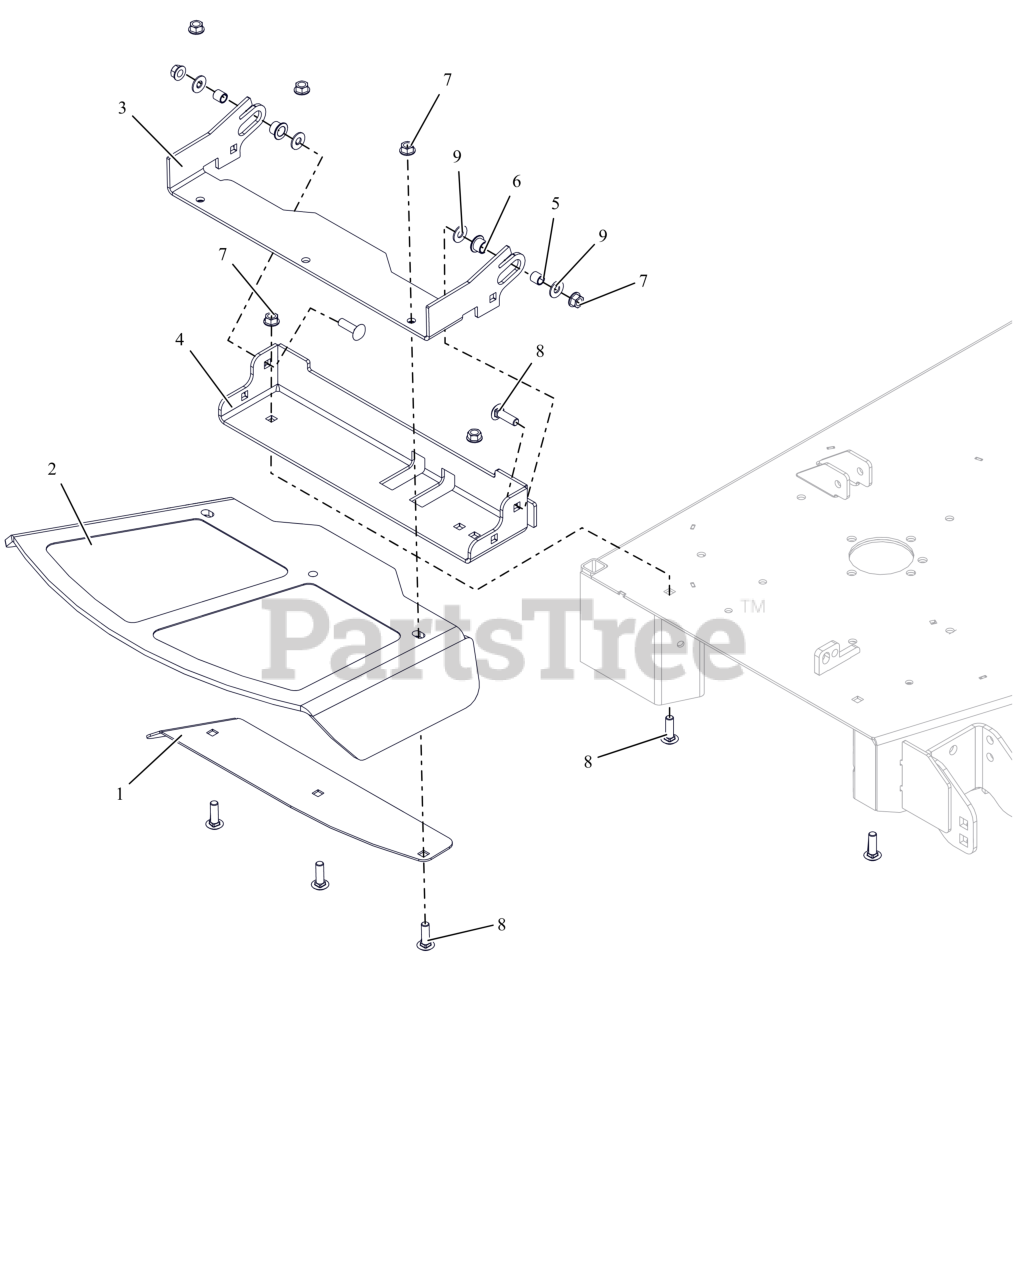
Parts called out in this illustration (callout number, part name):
1	48-60 DISCH CHUTE CLMP PLT-RED
2	CHUTE, FORMED RUBBER DISCHARGE
3	BRKT, CHUTE MOUNT (RED)
4	BASE, DISCHARGE CHUTE MTG BRKT (RED)
5	SPCR, .385X.500X.350
6	BSHG, FLANGED .50X.625X.50X.062
7	NUT-LK-CTR-FLG .375-16 GF ZCC
8	BLT,RHSSN .38-16X1.25 G5 ZCC
9	WSHR, HDND 0.375X0.875X0.064 ZCC
